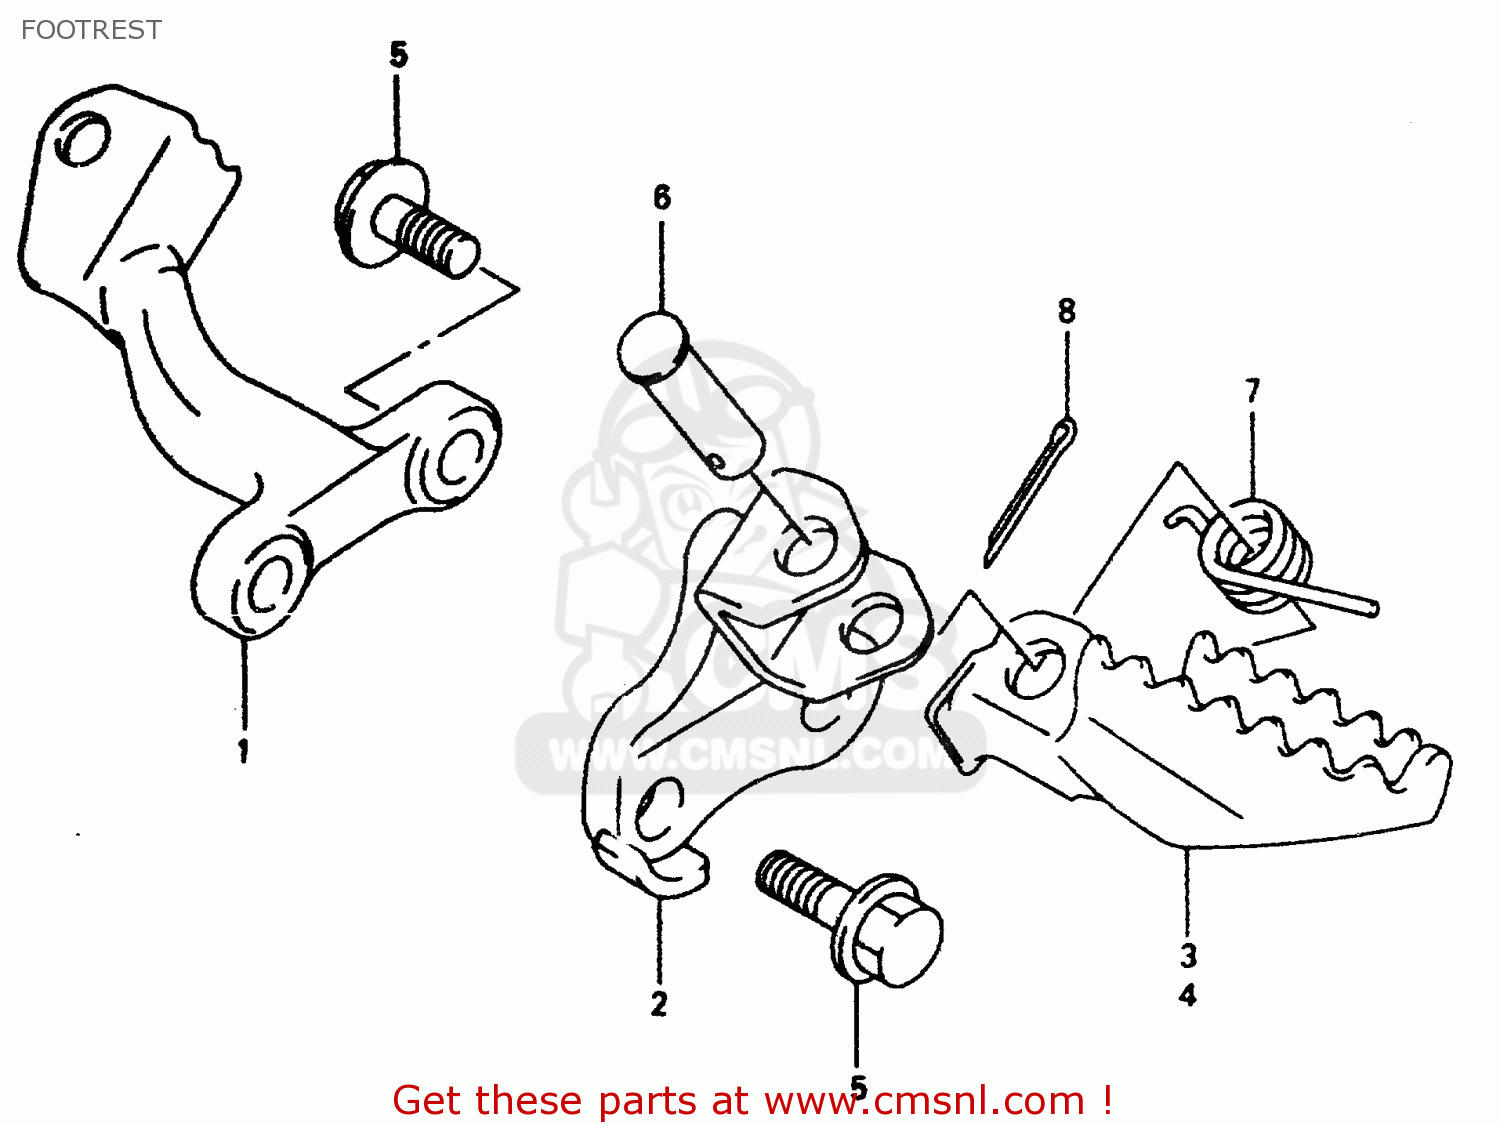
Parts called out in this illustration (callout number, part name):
1	BRACKET,FRONT FOOTREST
2	BRACKET,FR FOOTREST,L
3	FOOTREST,RIGHT
4	FOOTREST,LEFT
5	BOLT(10X40)
6	PIN
7	SPRING
8	PIN
